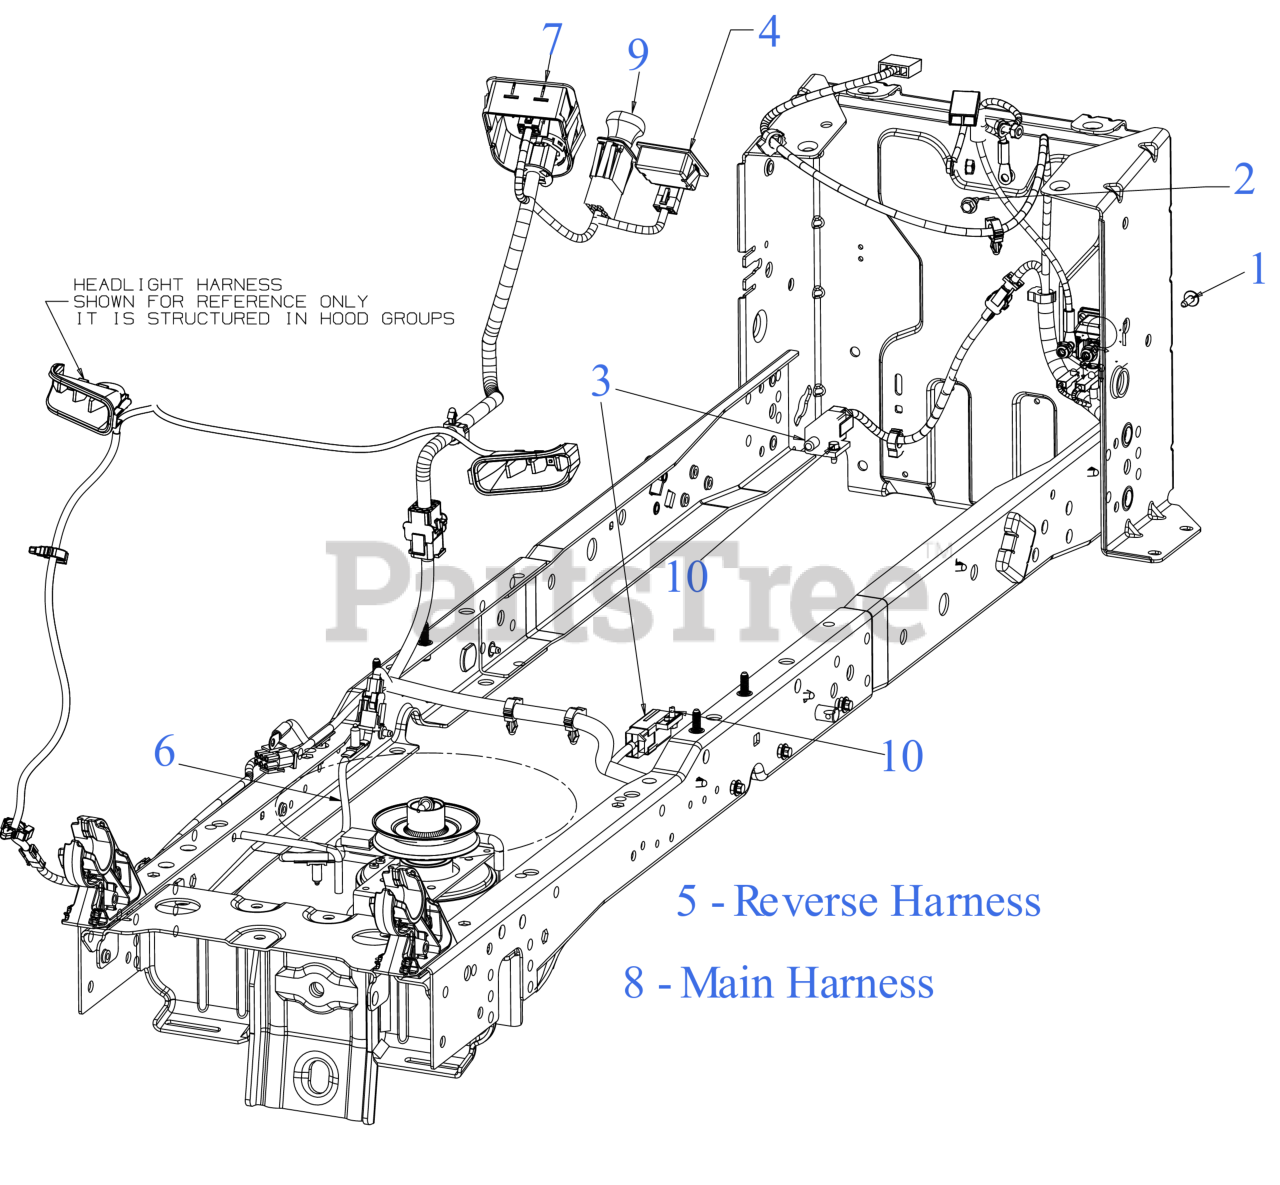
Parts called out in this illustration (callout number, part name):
1	SCREW M6-1 x .625
2	SCREW 1/4-20X.625
3	INTERLOCK SWITCH (NO/NC)
4	HOUR METER/SERVICE MINDER
5	REVERSE HARNESS
6	CLUTCH HARNESS 11"
7	IGNITION MODULE SWITCH (RMC ELC PTO WHTE)
8	HARNESS (EPTO/RMC/HRMTR/DC)
8	12V SOLENOID
9	PTO SWITCH (YELLOW KNOB)
10	SHOULDER SCREW
